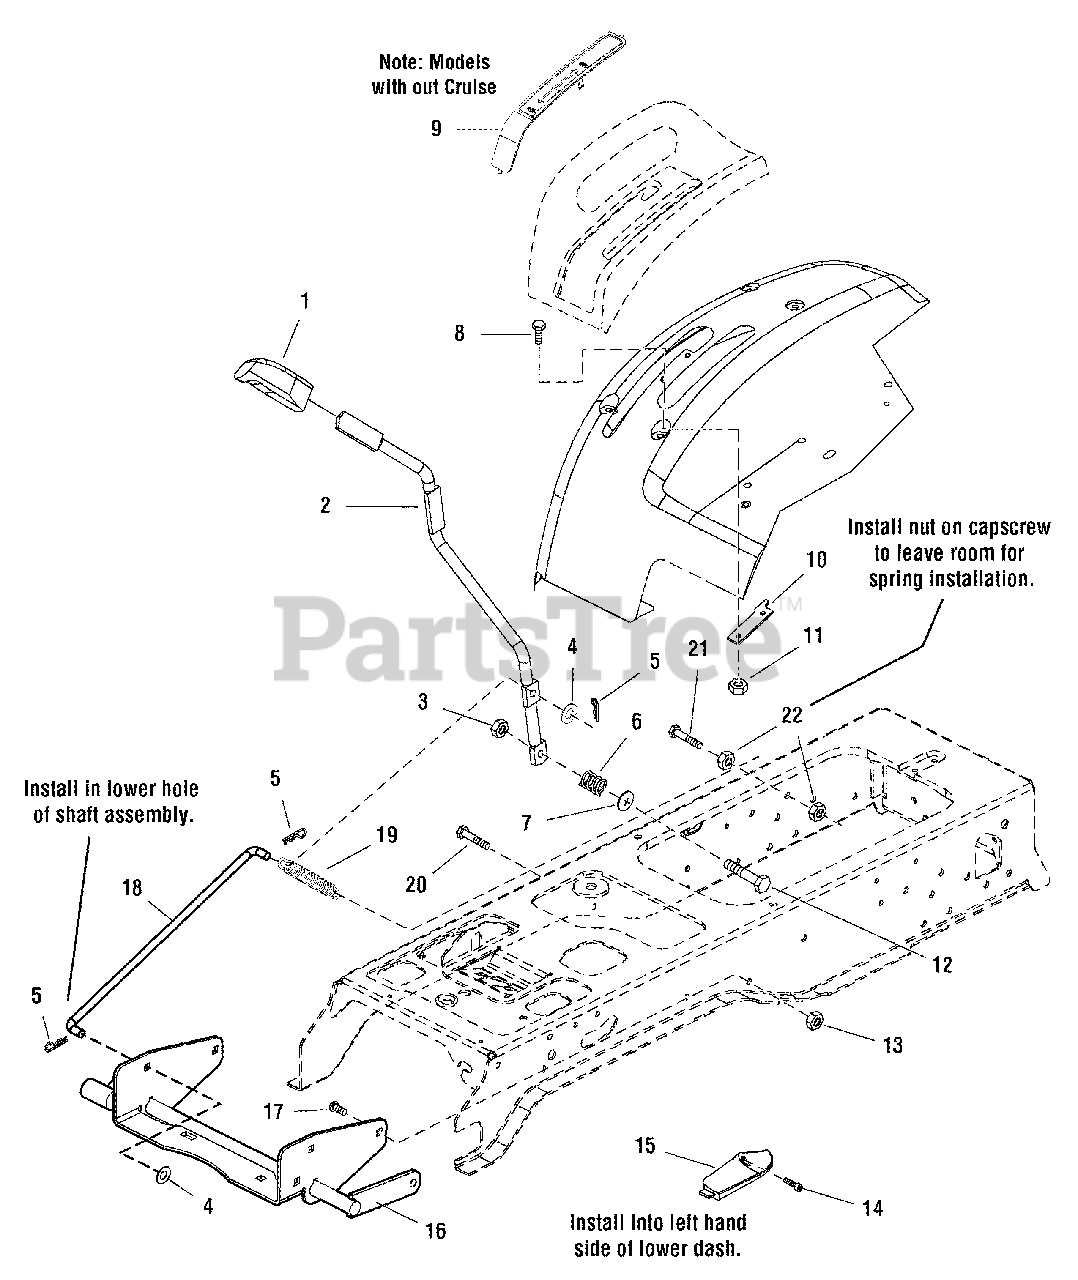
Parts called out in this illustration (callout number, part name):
1	GRIP, Black Vinyl
2	ROD, Lift Lever
3	NUT, Hex Flange Lock, 3/8-16
4	WASHER
5	PIN, Quick
6	SPRING, Compression
7	NUT, Push, 3/8
8	CAPSCREW, Hex Head, 1/4-20 x 3/4
9	COVER, W/Lift Icon, models without cruise
10	QUADRANT
11	NUT, Hex Lock ESNA, 1/4-20
12	CAPSCREW, Hex Head, 3/8-16 x 2
13	NUT, KEPS Lock, 5/16-18
14	SCREW, Torx Head, # 8-16 x 1/2
15	COVER, Dash, modles without cruise
16	LIFT SHAFT ASSEMBLY
17	CARRIAGE BOLT, 5/16-18 x 3/4
18	ROD, Lift
19	SPRING
20	CAPSCREW, Hex Head, 5/16-18 x 1-1/4
21	CAPSCREW, Hex Head, 3/8-16 x 1-3/4
22	NUT, KEPS Lock, 3/8-16
